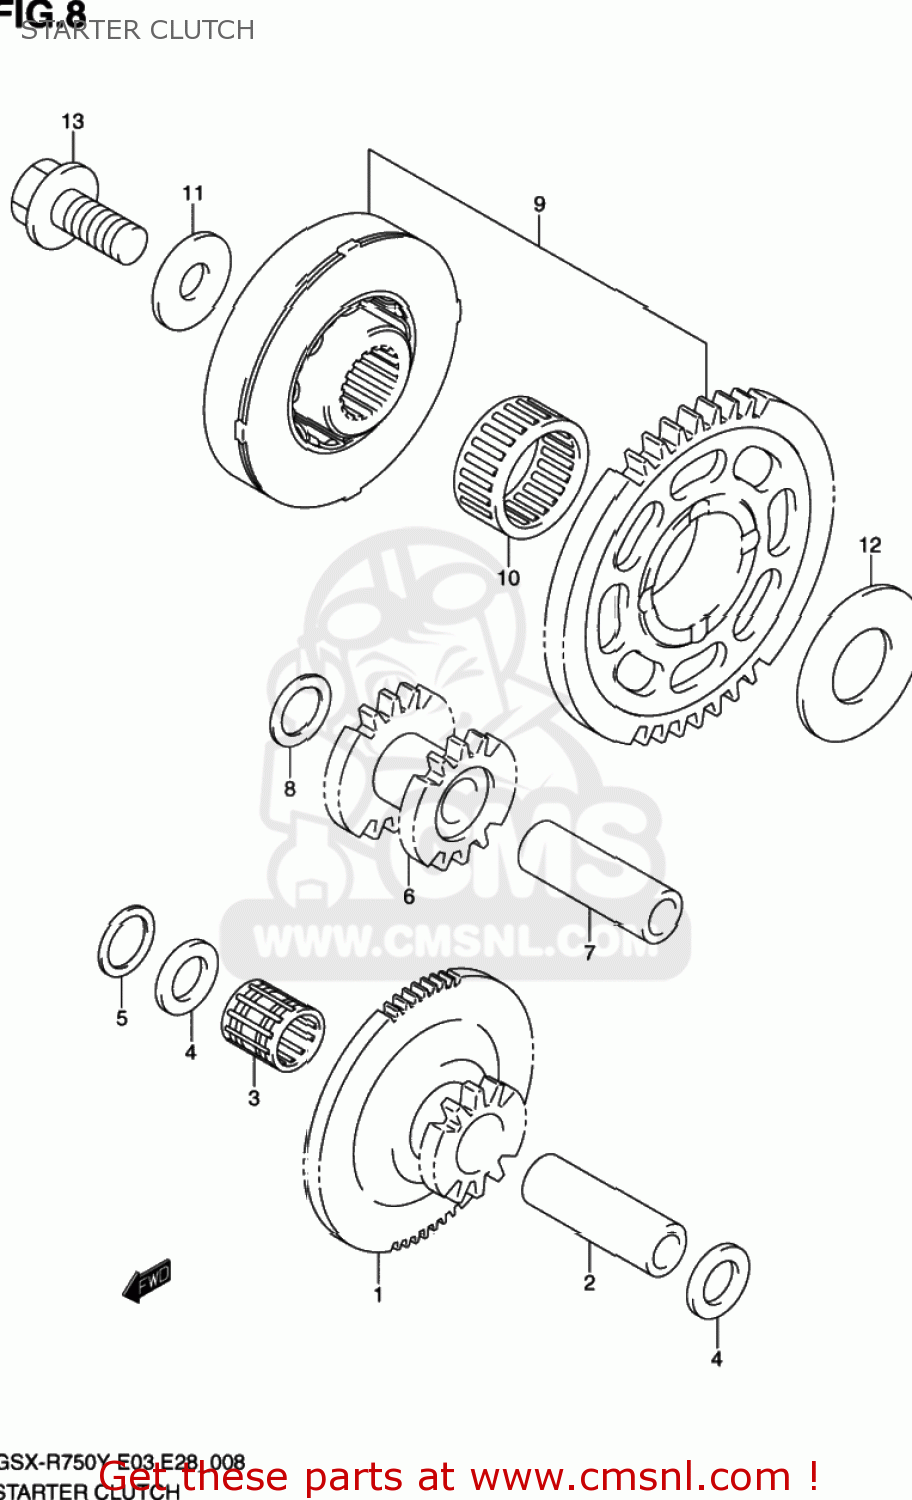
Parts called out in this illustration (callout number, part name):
1	GEAR,STARTER IDLE NO.1
2	PIN,PISTON
3	BEARING(12X16X16)
4	SHIM(12X20X1)
5	WASHER
6	GEAR,STARTER IDLE NO.2
7	PIN,PISTON
8	WASHER
9	CLUTCH SET,STARTER
10	BEARING(26X31X16)
11	WASHER
12	WASHER
13	BOLT(10X23)
